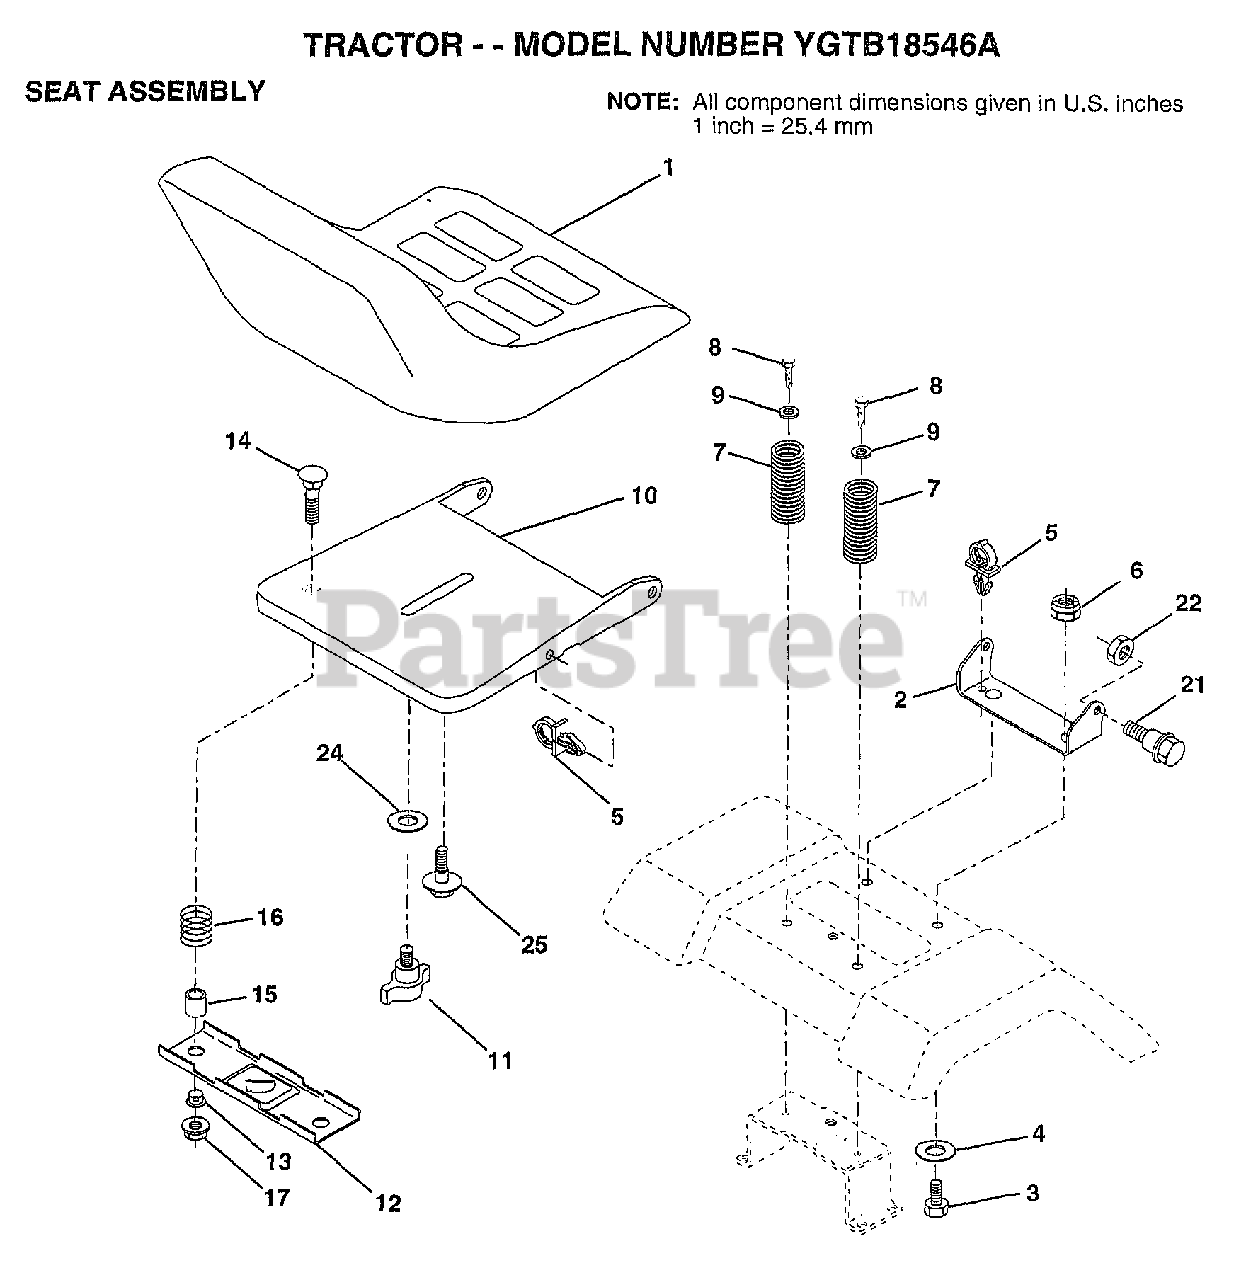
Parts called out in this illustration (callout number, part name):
1	SEAT.2500/1516.BK
2	BRACKET PVT SEAT
3	CLIP.PUSH-IN.HING
6	NUT
7	SPRING COMPRESSIO
10	PAN-SEAT
11	KNOB.SEAT.ADJ.WINGNUT
12	BRKT SWITCH
13	BUSHING
14	BOLT-RD HD SQ NK
15	SPACER SPLIT
16	SPRING COMPRESSED
21	"BOLT,SHOULDER"
24	WASHER
25	"BOLT,SHOULDER"
27	SCREW LT
28	BOLT.5/16-18.UNC
